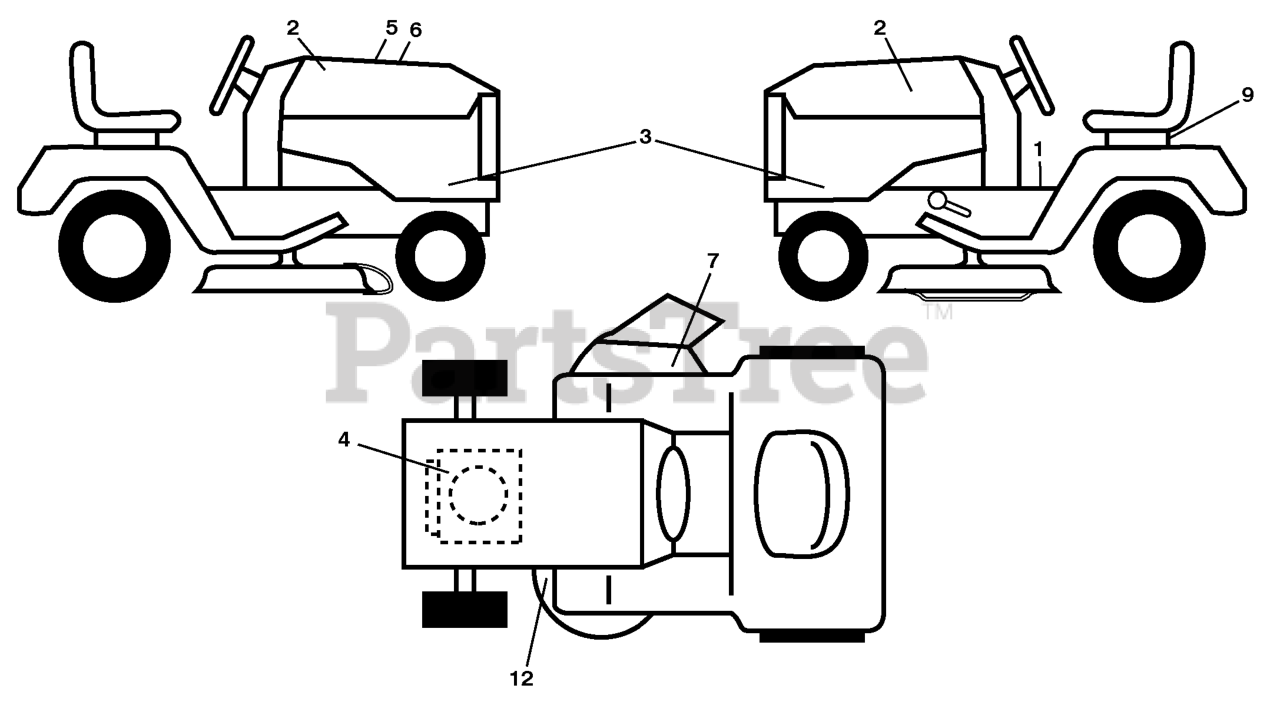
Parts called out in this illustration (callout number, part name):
1	DECAL.FENDER.WARNING.ENG
2	RP.DECAL.BADGE.170MM.TEXTLOGO
3	DECAL.SDPNL.YTH22V42.
4	DECAL.ENG.BS.22.XRD.TWN.278445
5	DECAL.WARNING.CUST.RESP.E85.
6	Decal, Replacement
7	DECAL.WARN.KEEP.HAND.AWAY
9	DECAL BTRY SYMBOLS
12	DECAL V BELT SCHEMATIC
